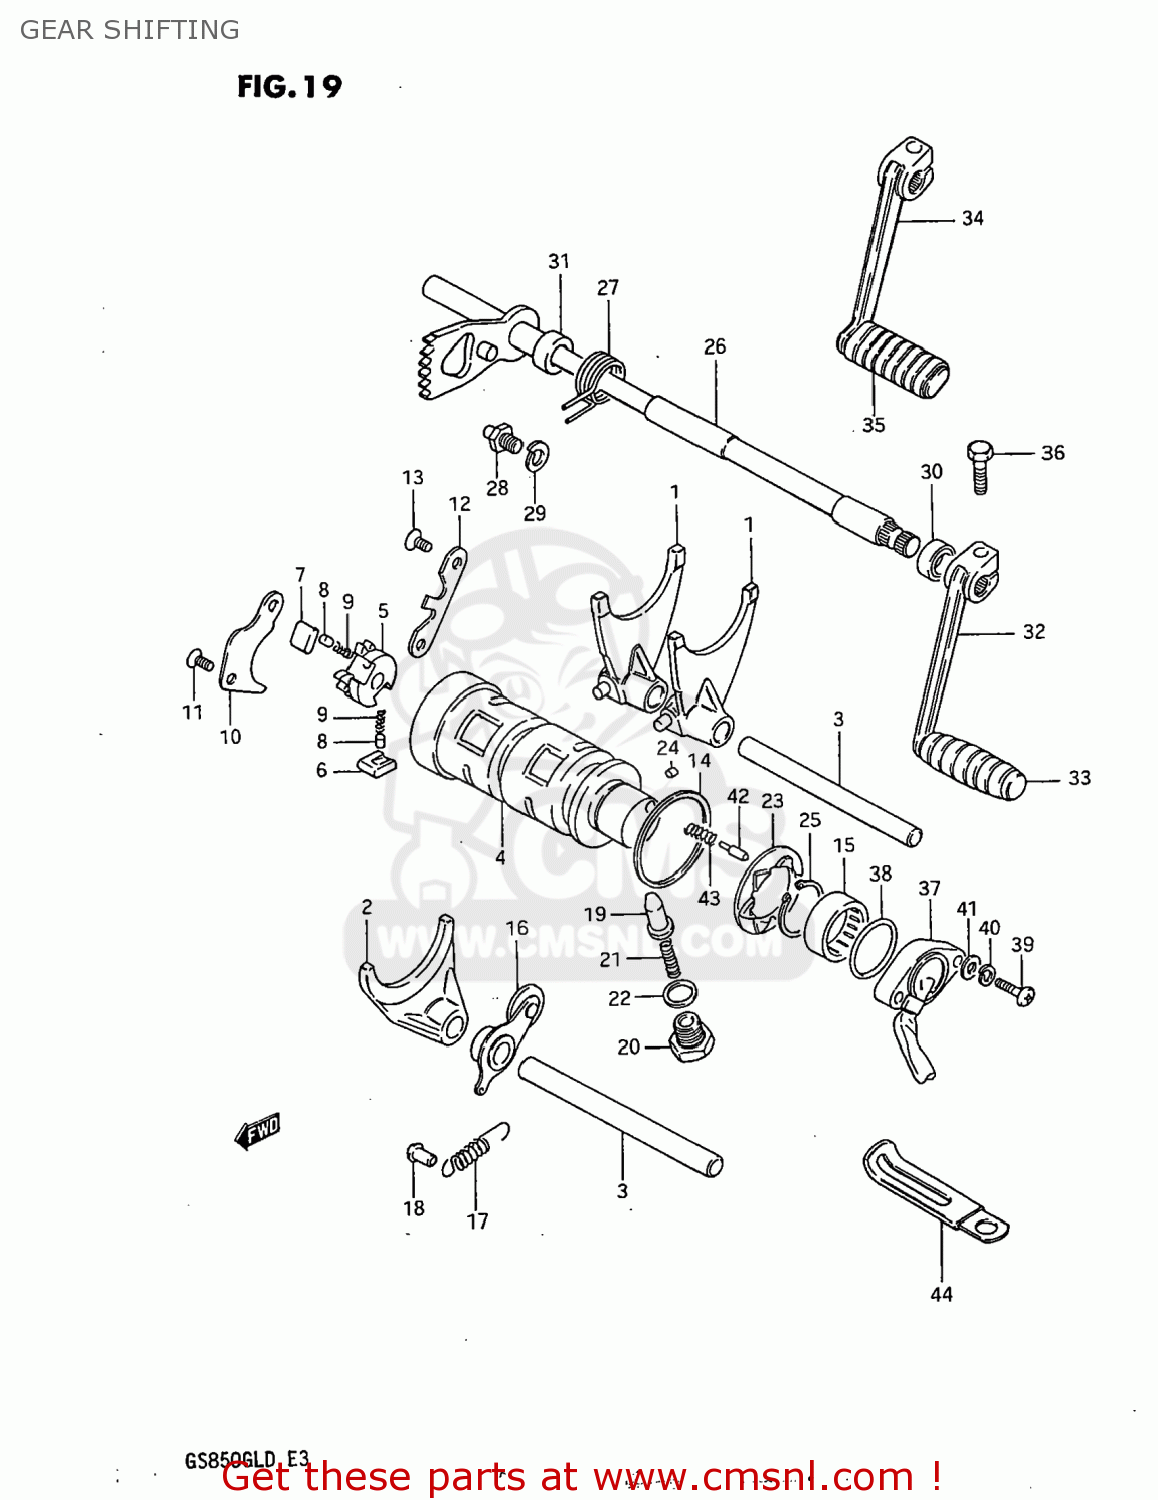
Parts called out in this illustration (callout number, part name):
1	FORK,GEAR SHIFT NO.1
2	FORK,GEAR SHIFT NO.3
3	SHAFT,GEAR SHIFT FORK
4	CAM,GEAR SHIFT
5	RETAINER,GEAR SHIFT CAM
6	PAWL,GEAR SHIFT NO.1
7	PAWL,GEAR SHIFT NO.2
8	PIN(5X8)
9	SPRING
10	LIFTER,GEAR SHIFT PAWL
11	SCREW
12	GUIDE,GEAR SHIFT CAM
13	SCREW
14	WASHER(40X45X1)
15	BEARING(25X32X12)
16	STOPPER,GEAR SHIFTING
17	SPRING
18	RIVET
19	STOPPER,GEAR SHIFT CAM NO.2
20	HOLDER,GEAR SHIFT CAM STOP SPR
21	SPRING
22	GASKET(14X19.2X2) (NAS)
23	PLATE,GEAR SHIFT CAM STOPPER
24	PIN 4X6
25	CIRCLIP,25MM
26	SHAFT,GEAR SHIFT
27	SPRING
28	STOPPER,GEAR SHIFT CAM
29	WASHER
30	OIL SEAL
31	SPACER (12X20X12)
32	LEVER ASSEMBLY,GEAR SHIFTING
33	RUBBER,GEAR SHIFT PEDAL
34	LEVER ASSY,GEAR SHIFT
35	RUBBER,PEDAL
36	BOLT
37	TERMINAL BASE ASSY,GEAR SHIFT
38	O-RING (D:2.4 ID:26.2)
39	SCREW 5X20
40	LOCK WASHER
42	WASHER
43	SPRING
44	CLAMP
